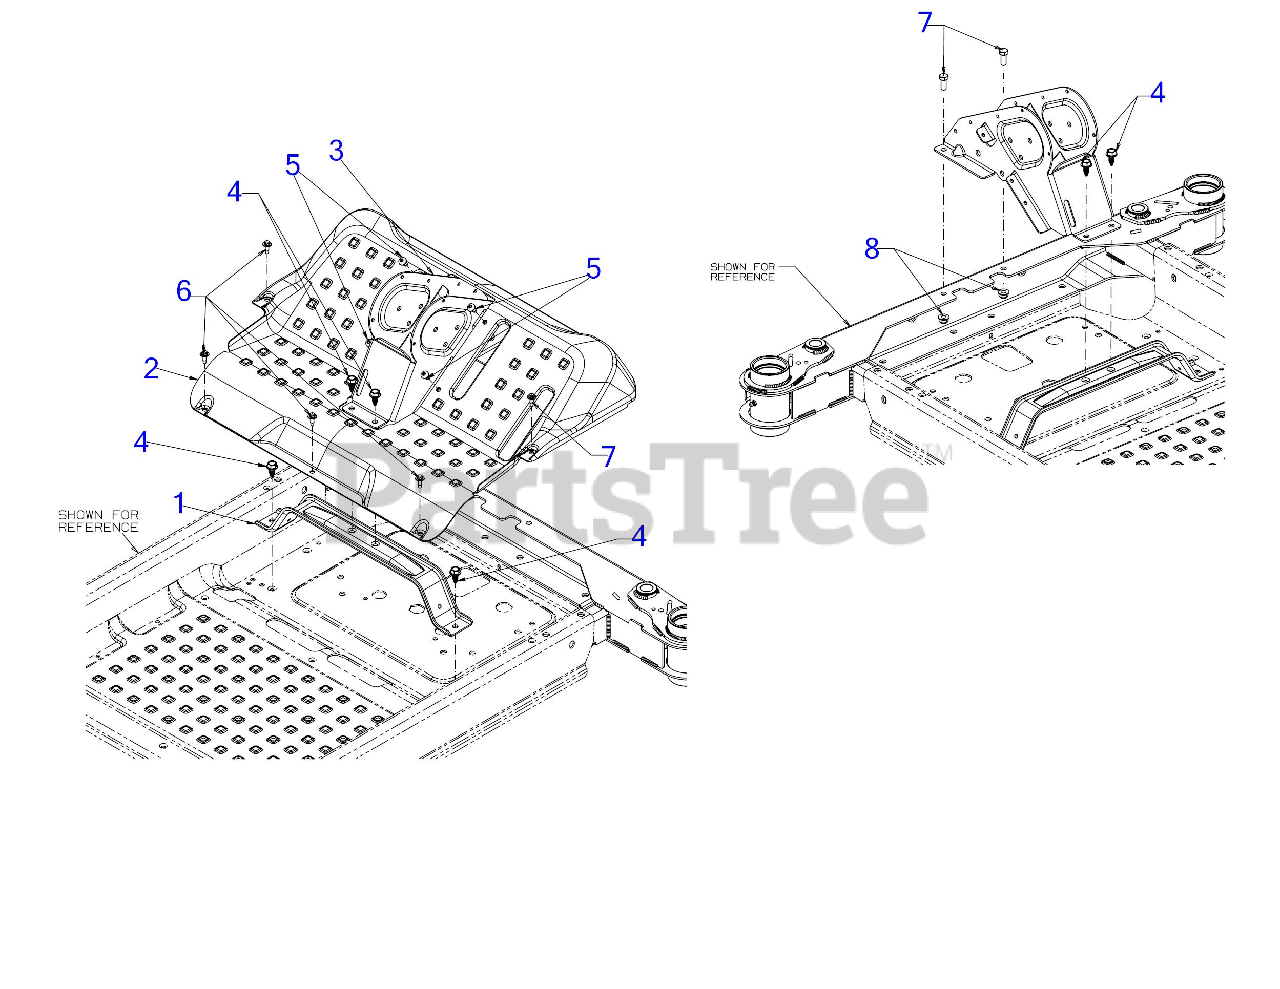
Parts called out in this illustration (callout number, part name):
3	LOWER STEERING COLUMN
4	SCREW 5/16-18 x .750
5	SCREW 1/4-20 x .5
6	SCREW M6-1 x .625
7	SCREW 5/16-18 x .75 GR5
8	FLANGE LOCK NUT 5/16-18
